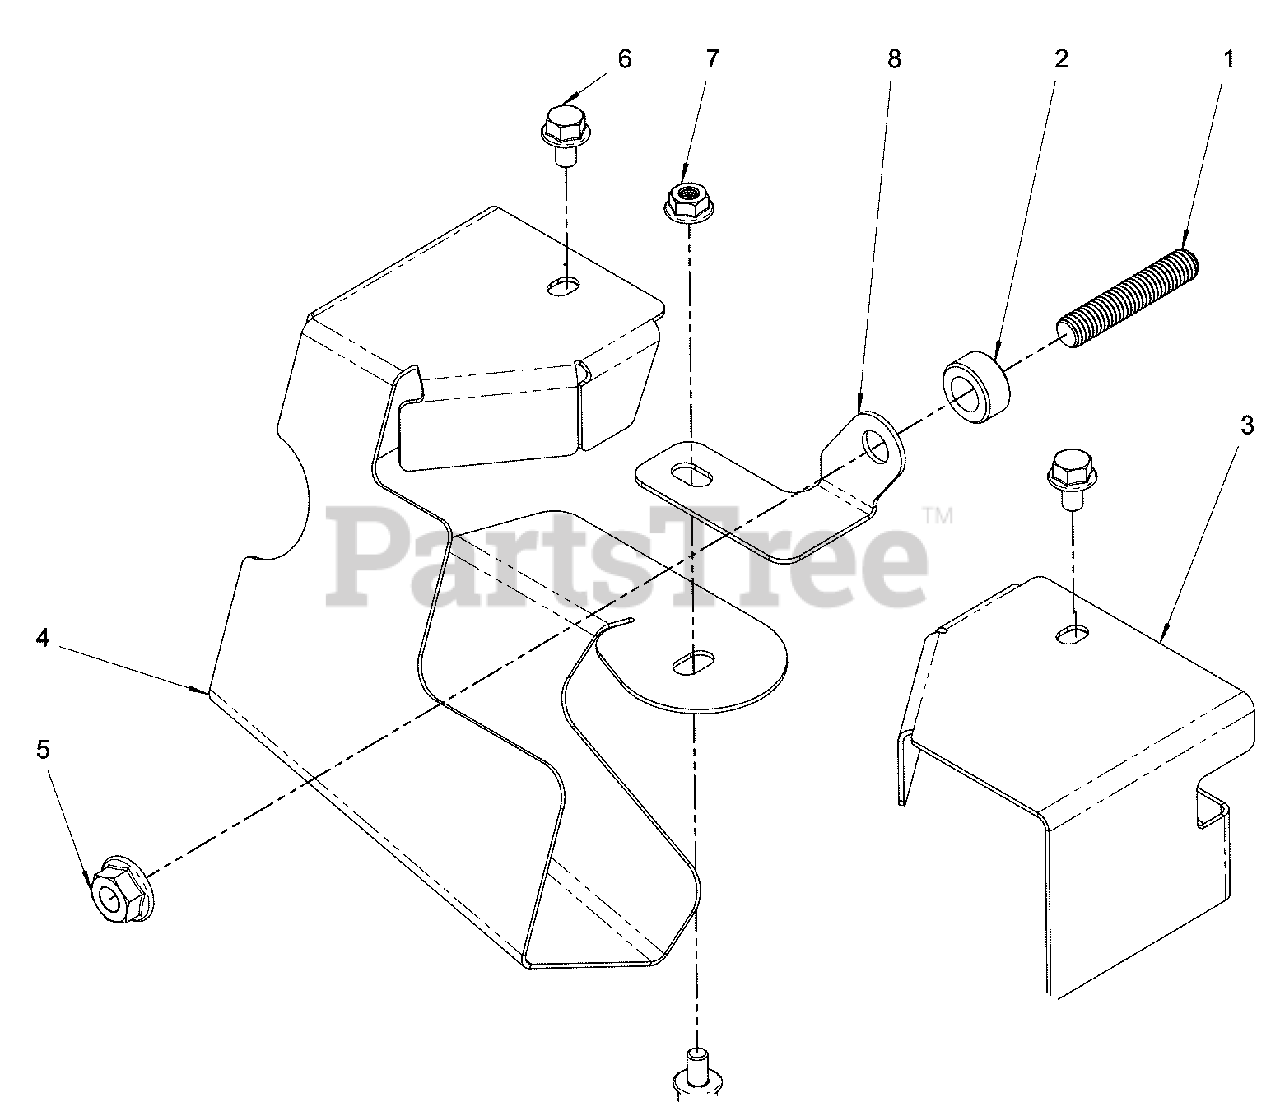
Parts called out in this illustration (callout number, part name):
1	* STUD
2	* SPACER
3	* EXHAUST HEAT SHIELD
4	* ALTERNATOR HEAT SHIELD
5	* NUT
6	* BOLT
7	* NUT
8	* BRACKET
